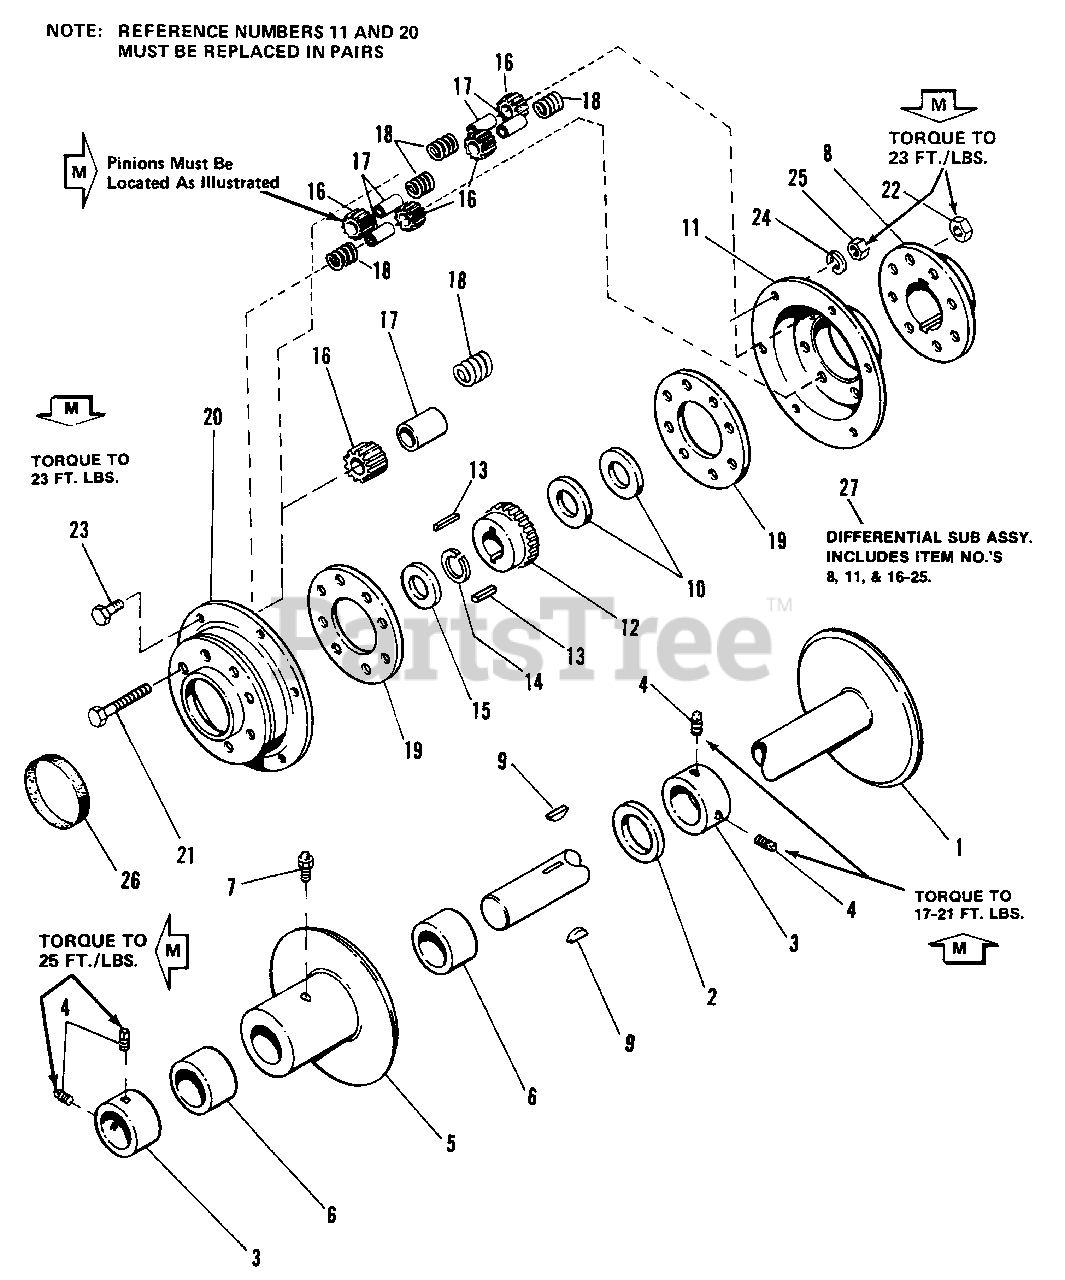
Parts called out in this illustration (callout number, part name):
1	REAR AXLE ASSEMBLY
3	COLLAR, Set
4	SETSCREW, Sq. Hd., 5/16-18 x 3/8
5	R.H.WHEEL HUB ASSEMBLY
7	FITTING, Grease
8	CARRIER, Diff.
10	WASHER, Axle
11	COVER, Diff.
12	GEAR, Diff.
13	KEY, Hi Pro, 1/4x3/4
14	RING, Retaining
15	WASHER, Axle
16	PINION, Diff.
17	SPINDLE, Diff. Pinion
19	RING, Spacer
20	COVER, Diff.
21	CAPSCREW, Hex Hd., 3/8-16 x 2-1/2
22	NUT, Hex, 3/8-16
23	CAPSCREW, Hex, 1/4-20 x 5/8
24	LOCKWASHER, 1/4
25	NUT, Hex, 1/4-14
26	SEAL, Cover
27	DIFFERENTIAL SUB ASSY. (Includes Item No.'s 8, 11, 16-25)
